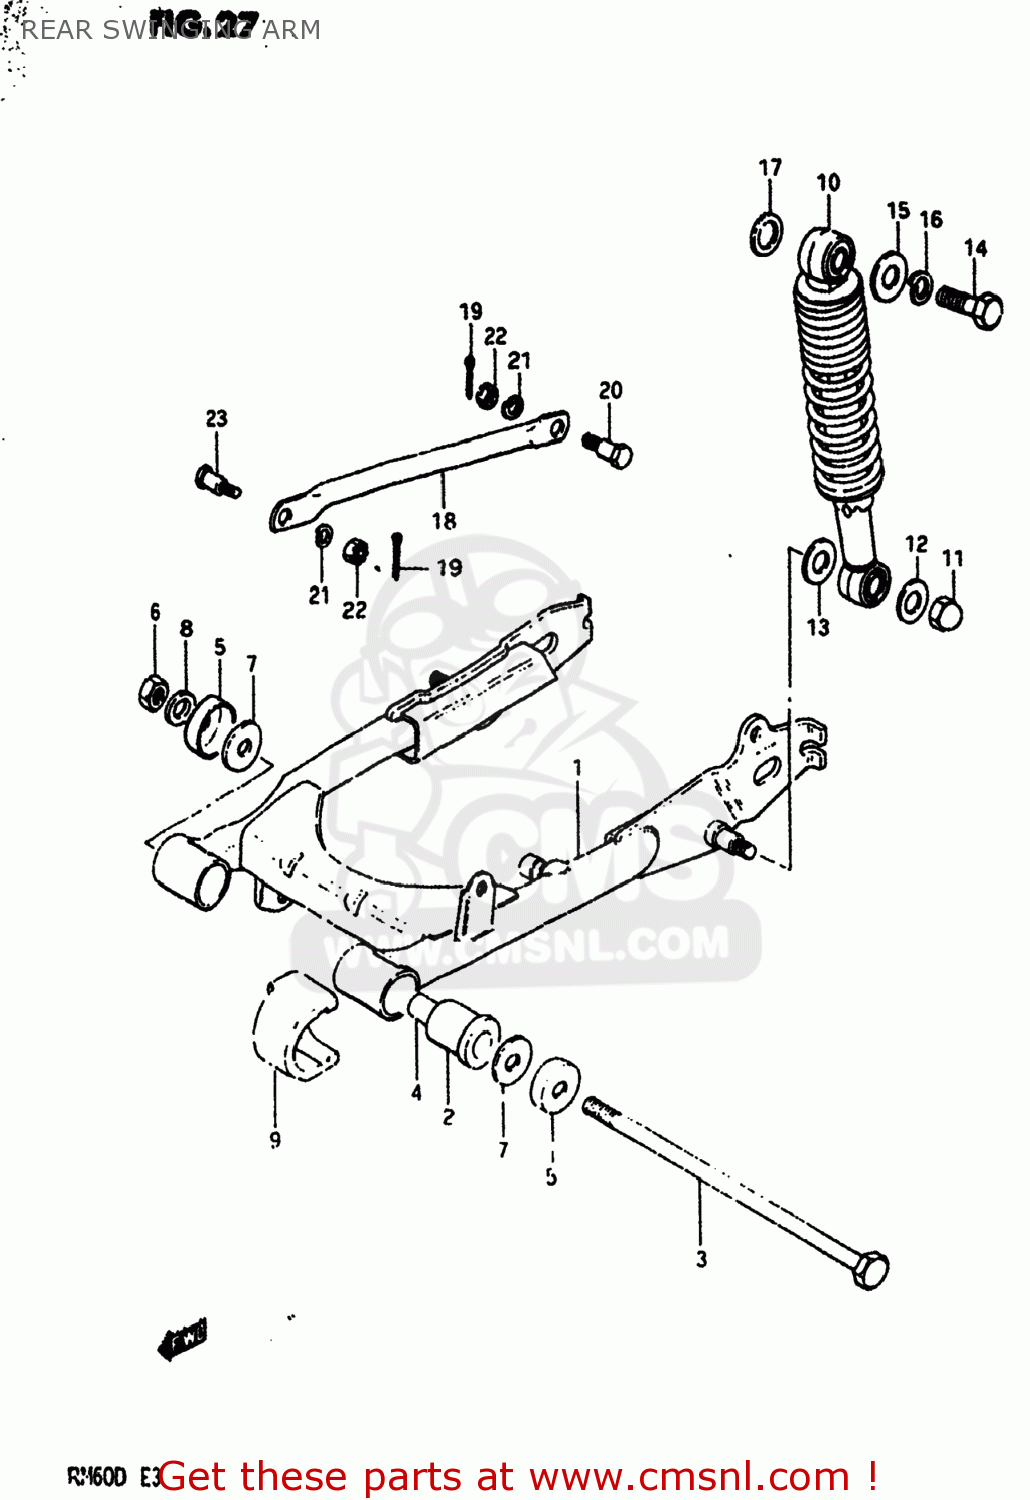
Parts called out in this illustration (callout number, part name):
1	SWING ARM ASSEMBLY,REAR
2	BUSHING
3	SHAFT, PIVOT
4	SPACER,RR SWGARM PIVOT
5	COVER,REAR SWING ARM DUST
6	NUT
7	WASHER (10.2X28X1.5)
8	WASHER
9	BUFFER,CHAIN TOUCH DEFLECTOR
10	ABSORBER ASSEMBLY,REAR SHOCK
11	NUT, LOWER LH
12	WASHER
13	WASHER
14	BOLT
15	WASHER (6.5X24X1.6)
16	LOCK WASHER
17	WASHER
18	TORQUE LINK,REAR
19	COTTER PIN
20	BOLT(8X26.5)
21	LOCK WASHER
22	NUT
23	BOLT(8X22)
